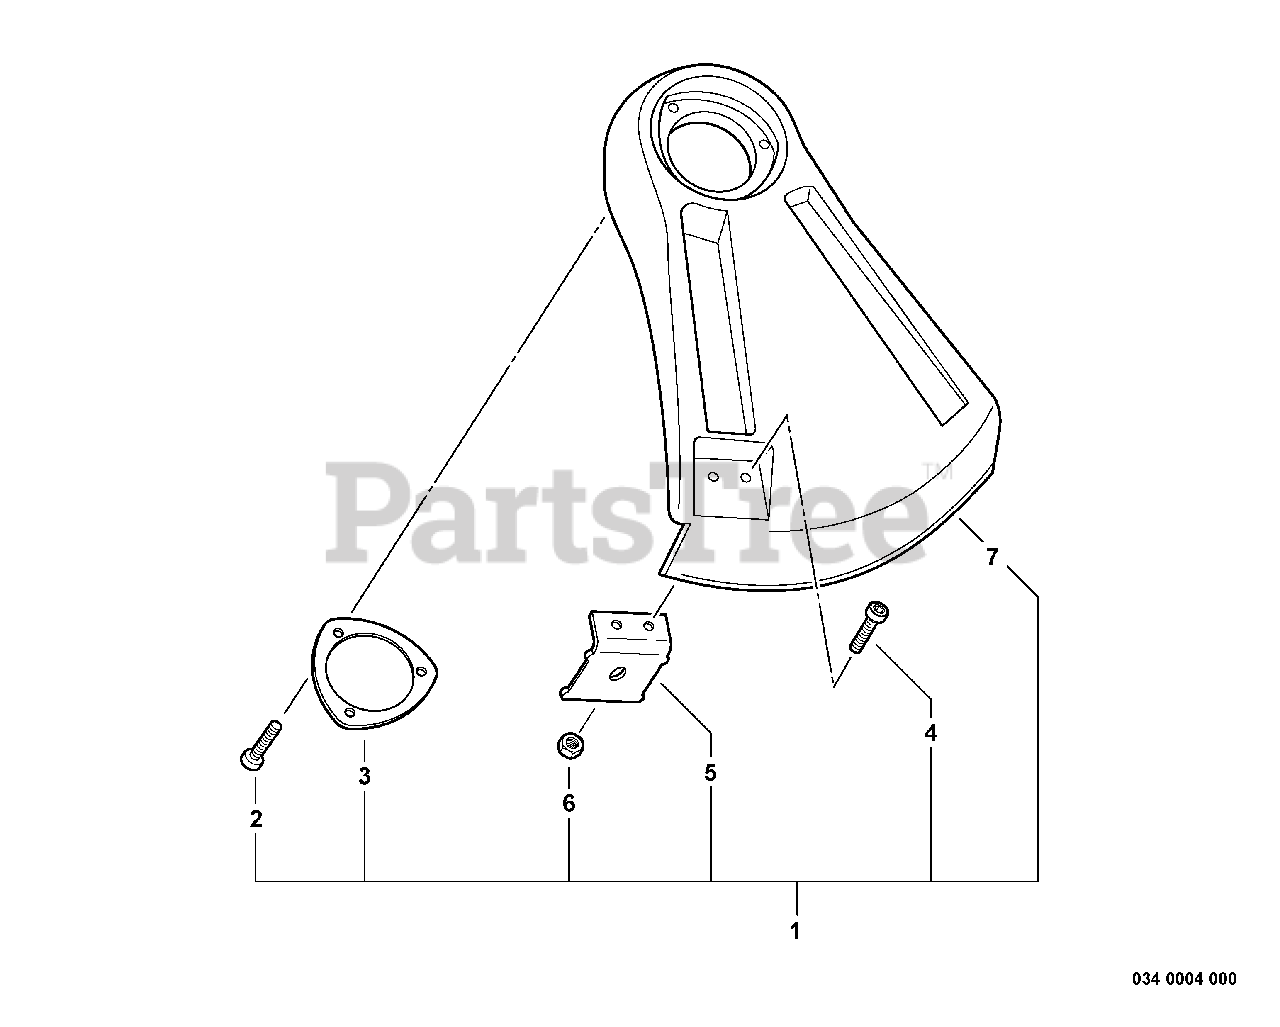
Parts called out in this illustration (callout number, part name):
1	DEBRIS SHIELD KIT
2	BOLT, TORX 5×16
3	PLATE, SHIELD Ø49.5 MM
4	BOLT, TORX 5×12
5	CUTTER, LINE
6	NUT M5
7	SHIELD, DEBRIS
